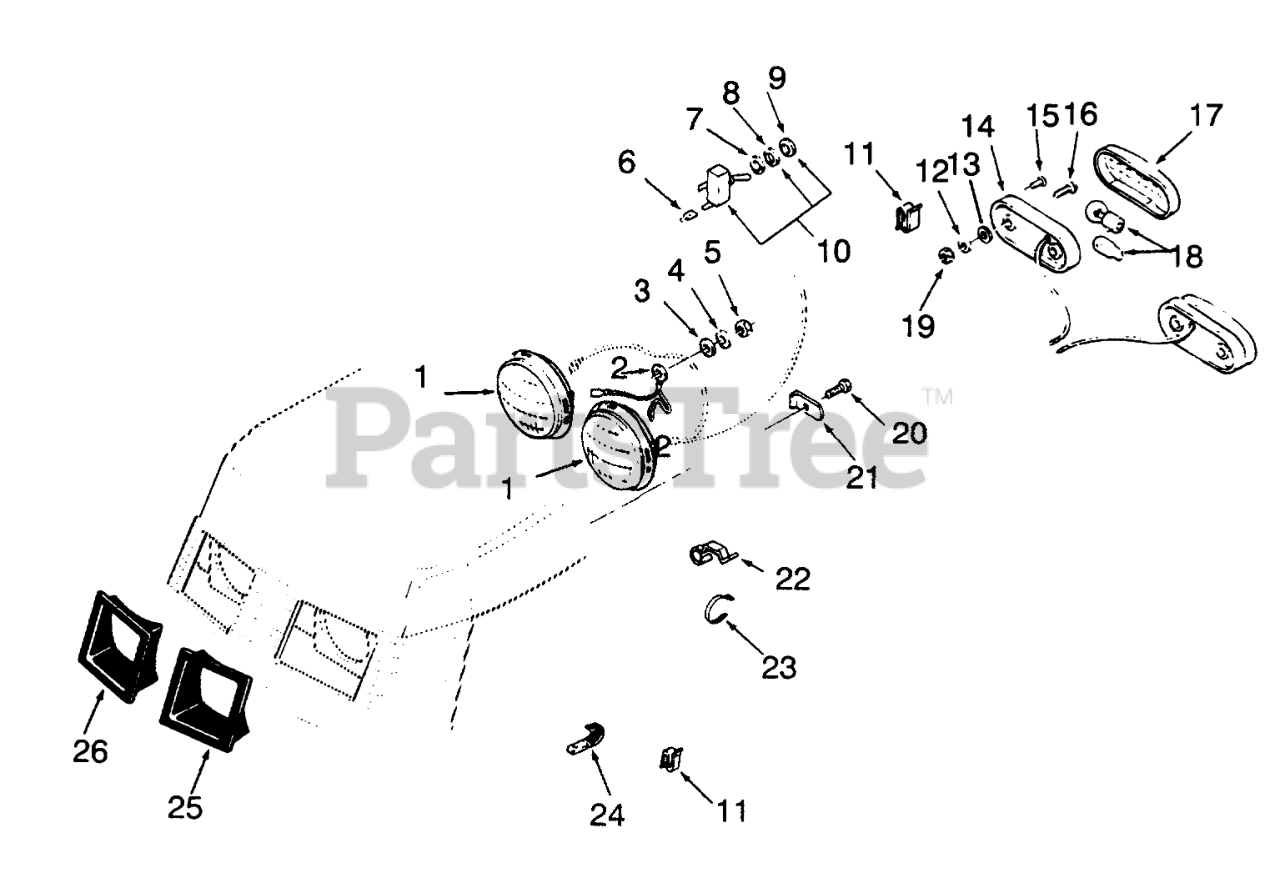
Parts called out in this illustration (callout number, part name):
1	HEADLAMP
2	LIGHT GROUND WIRE
3	WASHER-PLAIN
4	WASHER-LOCK, INTERNAL
5	NUT-LOCK, NI
6	Terminal
7	Washer
8	TAB-WASHER
10	SWITCH-LIGHTS
11	SPEED CLIP
12	WASHER-FLAT
13	WASHER-LOCK, INT
14	BASE-TAIL LIGHT
15	RIVET-POP
16	Screw
17	LENS-TAIL LIGHT
18	Bulb
19	Nut
20	Bolt
21	LOCK-HEADLIGHT
22	CLIP-WIRE
23	PLASTIC TIE
24	CLIP
25	BEZEL-HEADLIGHT, LH
26	BEZEL-HEADLIGHT, RH
